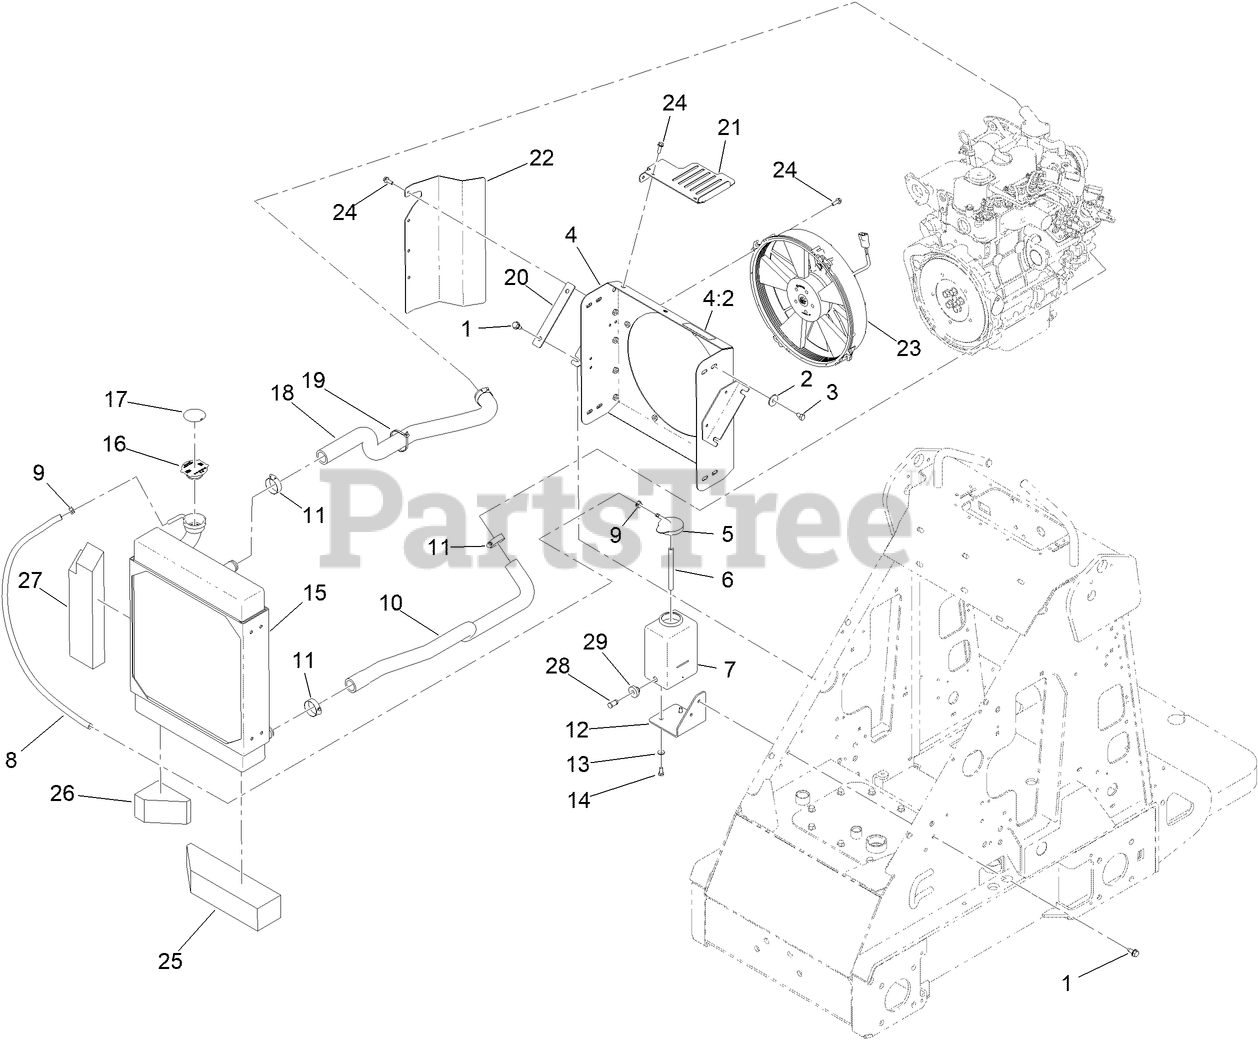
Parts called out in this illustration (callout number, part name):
1	SCREW-HWHTF
2	WASHER-FLAT
3	SCREW-HH
4	MOUNT-RADIATOR
4:2	DECAL-WARNING
5	CAP-TANK, OVERFLOW
6	HOSE-FUEL
7	TANK-OVERFLOW
8	HOSE-FUEL
9	CLAMP-HOSE
10	HOSE-RADIATOR, LOWER
11	CLAMP-HOSE
12	MOUNT-TANK,OVERFLOW
13	WASHER-FLAT
14	SCREW-HH LOCK
15	RADIATOR
16	CAP-RADIATOR
17	DECAL-WARNING
18	HOSE-RADIATOR, UPPER
19	TIE-CABLE
20	PLATE-CLAMP, RADIATOR
21	FAN-GUARD
22	PLATE-BAFFLE
24	SCREW-HHF
25	FOAM-SEAL
26	FOAM-SEAL
27	SEAL-FOAM
28	PLUG-GROMMET
29	BUSHING
